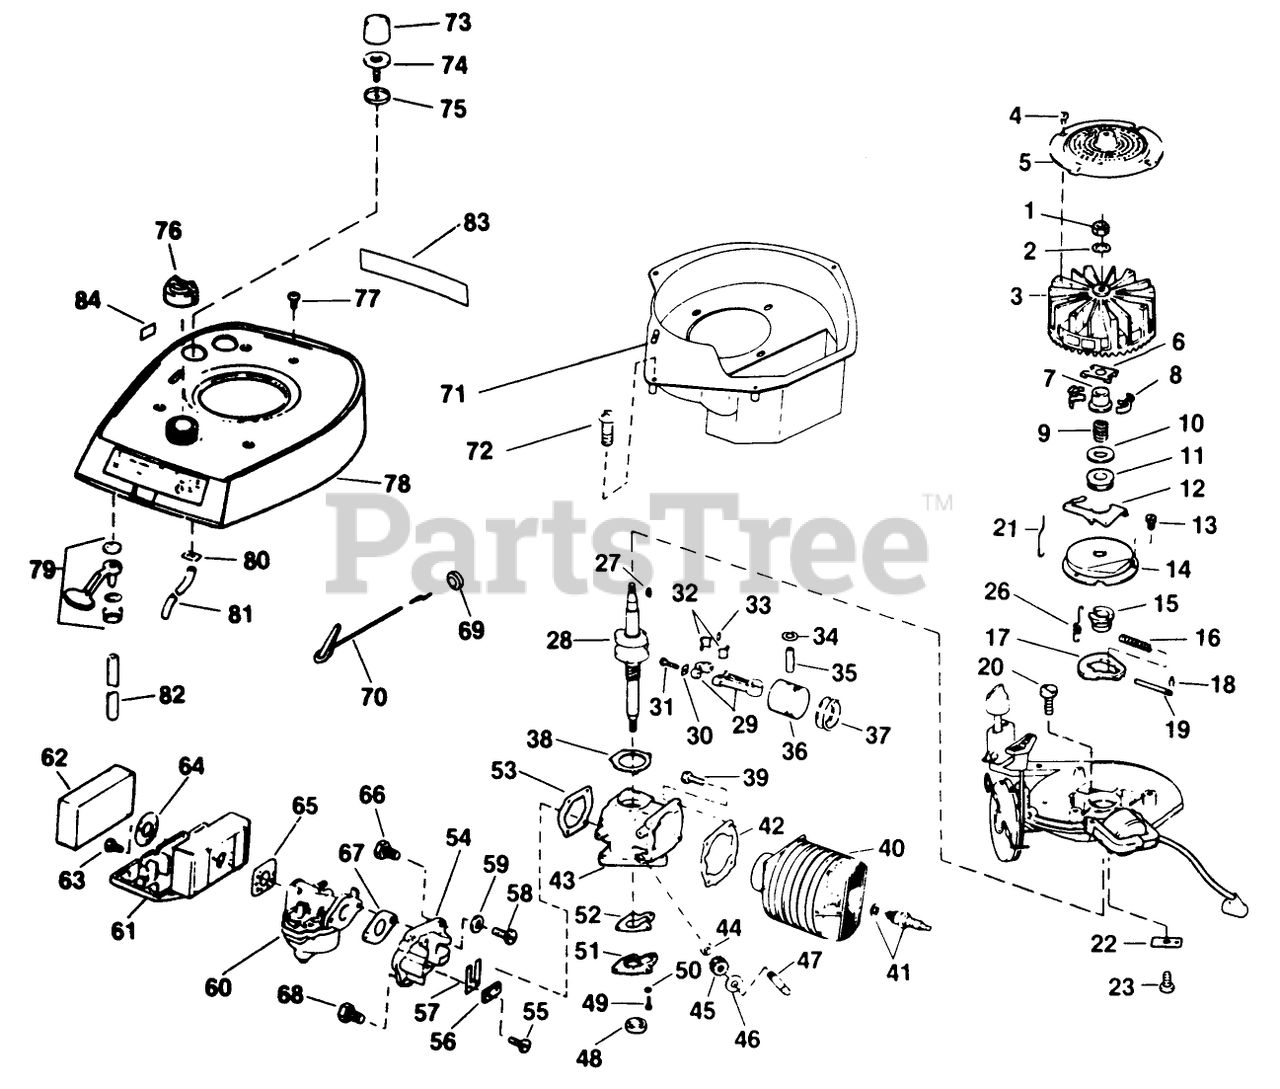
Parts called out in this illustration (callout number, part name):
4	SCREW F
5	FLYWHEEL SCREEN
7	COLLAR S
9	SPRING S
11	THRUST COLLAR S
12	LEVER-GOVERNOR S
13	SCREW S
14	DUST COVER S
15	SPARK ADV. S
16	Spring-Spark Advance
17	FLYWEIGHT S
18	SPARK ADJ. SPRING
19	PIN,SPARK ADV. S
23	SCREW S
31	Screw-Connecting Rod
32	LINER ASM
34	RING-RETAINING
38	GASKET S
41	Spark Plug Gasket
42	GASKET S
45	GEAR, DR SHAFT S
46	THRUST WASHER
51	GEAR COVER S
52	GASKET-CVR S
53	GASKET S
54	REED PLATE AY. S
56	PLATE-BACKUP, REED
62	AIR FILTER S
63	SCREW S
64	WASHER S
65	GASKET S
66	SCREW S
67	GASKET S
68	SCREW S
69	GROMMET
70	KNOB & ROD AY. S
75	CUP-BULB
77	SCREW S
80	LOCKNUT S
